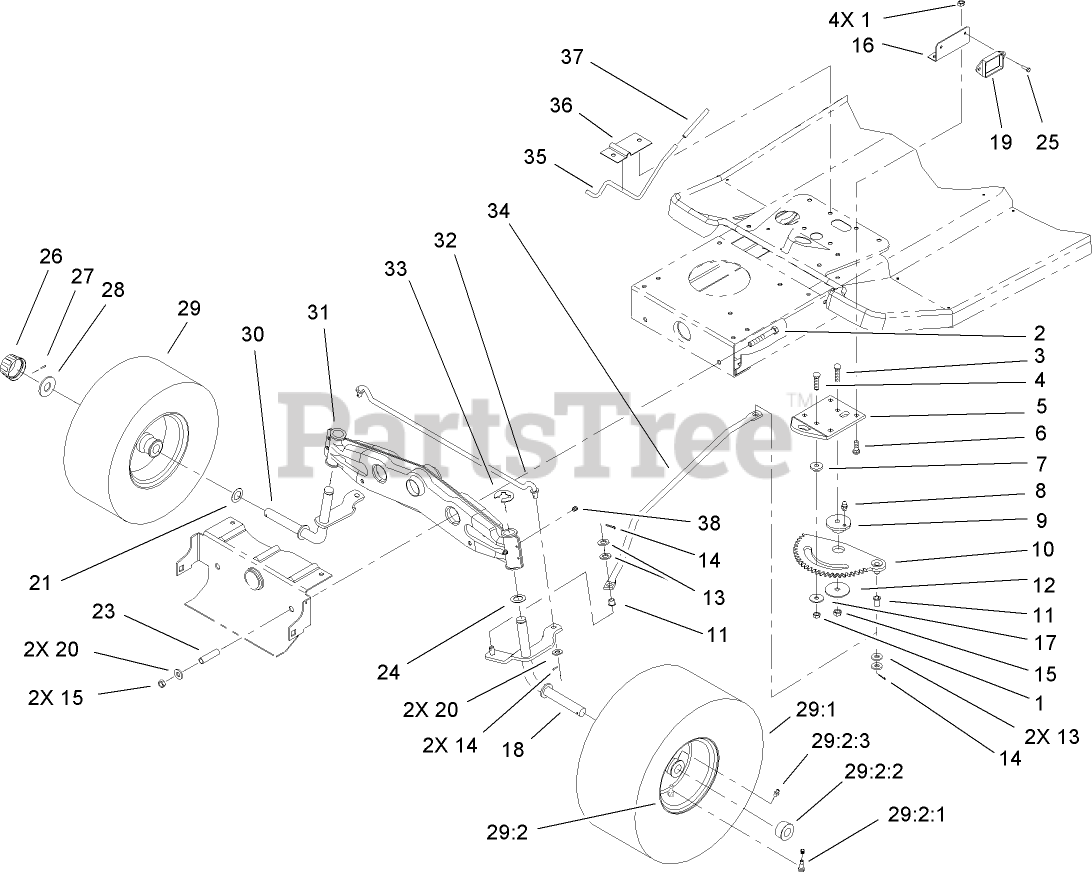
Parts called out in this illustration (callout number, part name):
1	NUT-LOCK, NI
2	SCREW-HH
3	SCREW-CARR
4	SCREW-CARR
5	BRACKET-RACK, STEERING
6	BOLT-CARR
7	SPACER-RACK, STEERING
8	FITTING-GREASE
9	BUSHING-ECCENTRIC
10	RACK-STEERING
11	BUSHING-FLANGED, NYLON
12	WASHER-BEARING
13	WASHER-FLAT
14	PIN-COTTER
15	NUT-LOCK, NI
16	BRACKET-MODULE
17	WASHER-PIVOT
18	LH SPINDLE ASM
19	MODULE
20	WASHER-FLAT
21	WASHER-THRUST
23	SPACER
24	WASHER-THRUST
25	SCREW-HWH
26	CAP-HUB
27	PIN-COTTER
28	WASHER-PLAIN
29	FRONT WHEEL and TIRE ASM
29:2	RIM ASM
29:2:1	STEM-VALVE
29:2:2	BEARING-WHEEL
29:2:3	FITTING-GREASE
30	RH SPINDLE ASM
31	FRONT AXLE ASM
32	TIE ROD-STEERING
33	E-RING
34	LINK-DRAG
35	ROD-BRAKE, PARKING
36	BRACKET-PARKING BRAKE
37	GRIP-BRAKE, PARKING
38	FITTING-GREASE
